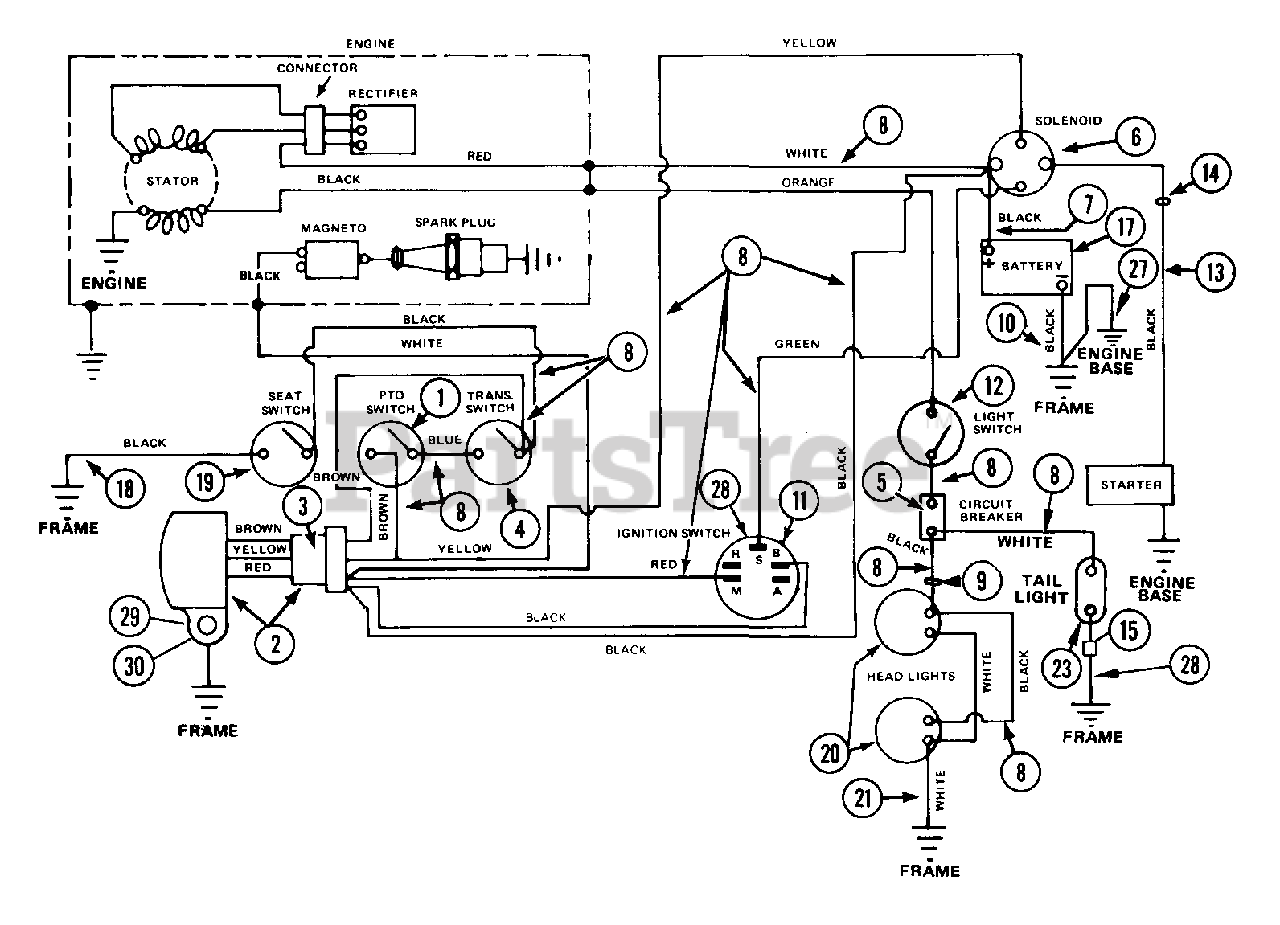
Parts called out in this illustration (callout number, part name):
1	SWITCH INTERLOCK
2	MODULE
3	CONNECTOR
4	SWITCH-NEUTRAL START N.O.
5	CIRCUIT BREAKER
6	SOLENOID
7	GROUND CABLE
8	WIRE HARNESS
9	CLAMP LOOP
10	GROUND CABLE
11	IGNITION SWITCH AND KEY ASSEMB
12	LIGHT SWITCH
13	GROUND CABLE
14	TIE DOWN
15	WIRE CLIP
17	BATTERY
18	GROUND WIRE
19	SWITCH SEAT
20	HEAD LIGHT
21	GROUND WIRE
22	TAIL LIGHT WIRE
23	TAIL LIGHT
23	TAIL LIGHT LENS
27	GROUND CABLE
28	GROUND WIRE
29	SCR-MCH 10-24X.62 SLRH PL
30	NUT-KEPS 10-24 PL
30	WSHR-LK .312X.097 PL HVY
30	NUT-JAM .312-24 PL
30	WSHR-LK 10X.047 MED PL
30	NUT 10-32 PL
